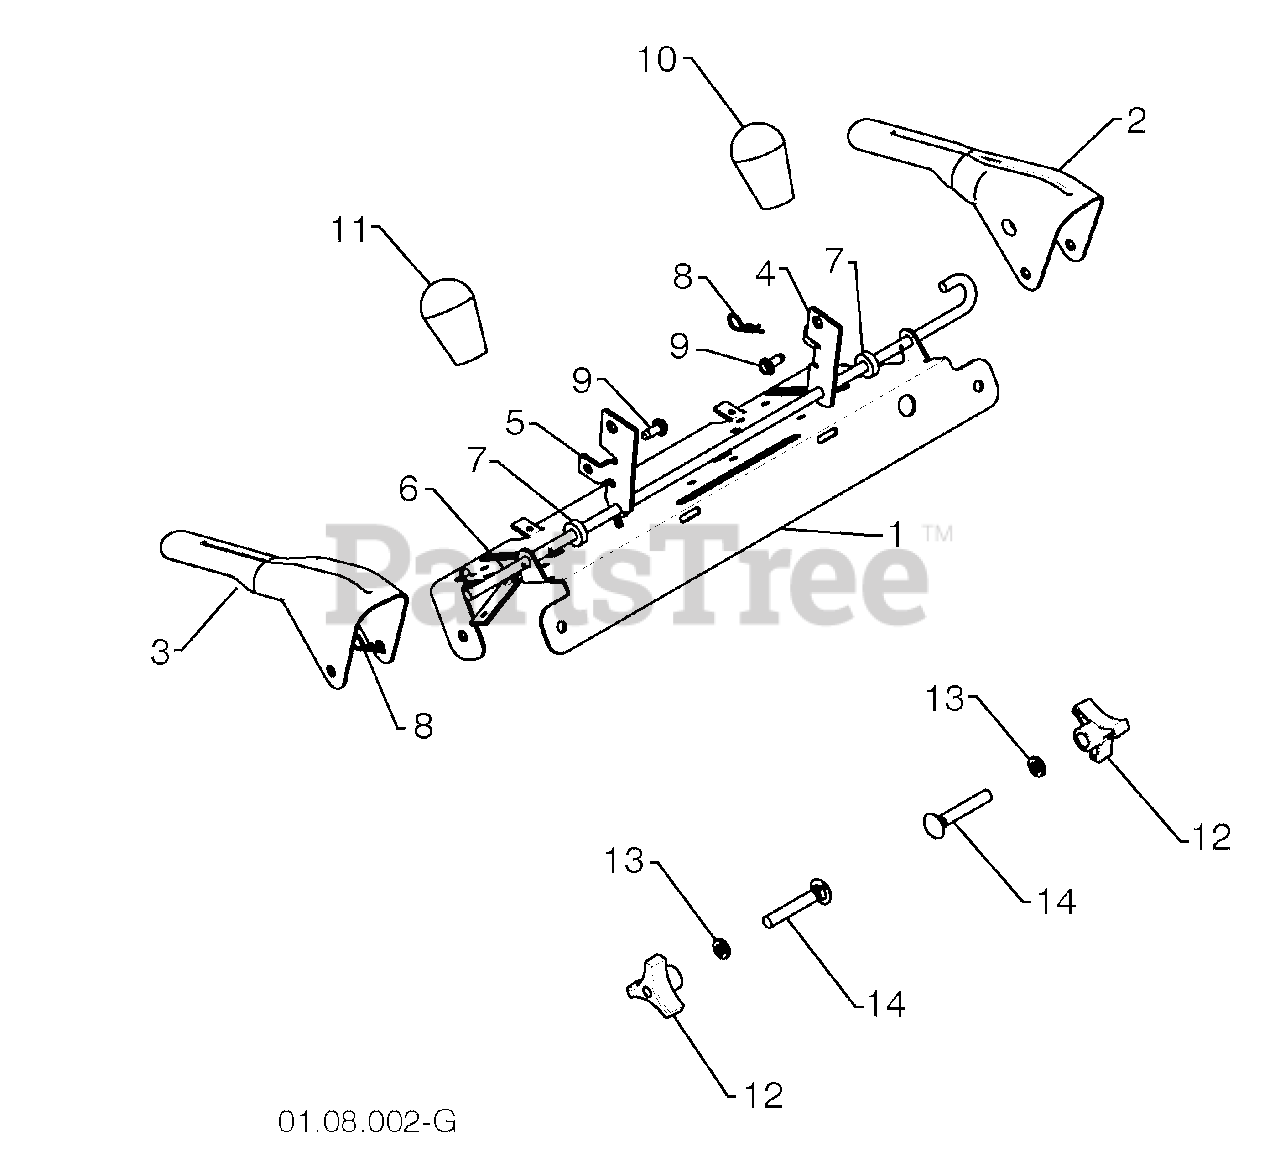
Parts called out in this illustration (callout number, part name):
2	CONTROL LEVER LH
3	CONTROL LEVER RH
4	TRACTION ROD ARM
5	IMPELLER ROD ARM
6	INTERLOCK ROD
8	RETAINER
9	SCREW 1/4-20 X .62
10	KNOB BLACK
11	KNOB RED
12	HANDLE KNOB
13	WASHER 3/8
14	CARRIAGE BOLT 3/8-16 X 2.25
